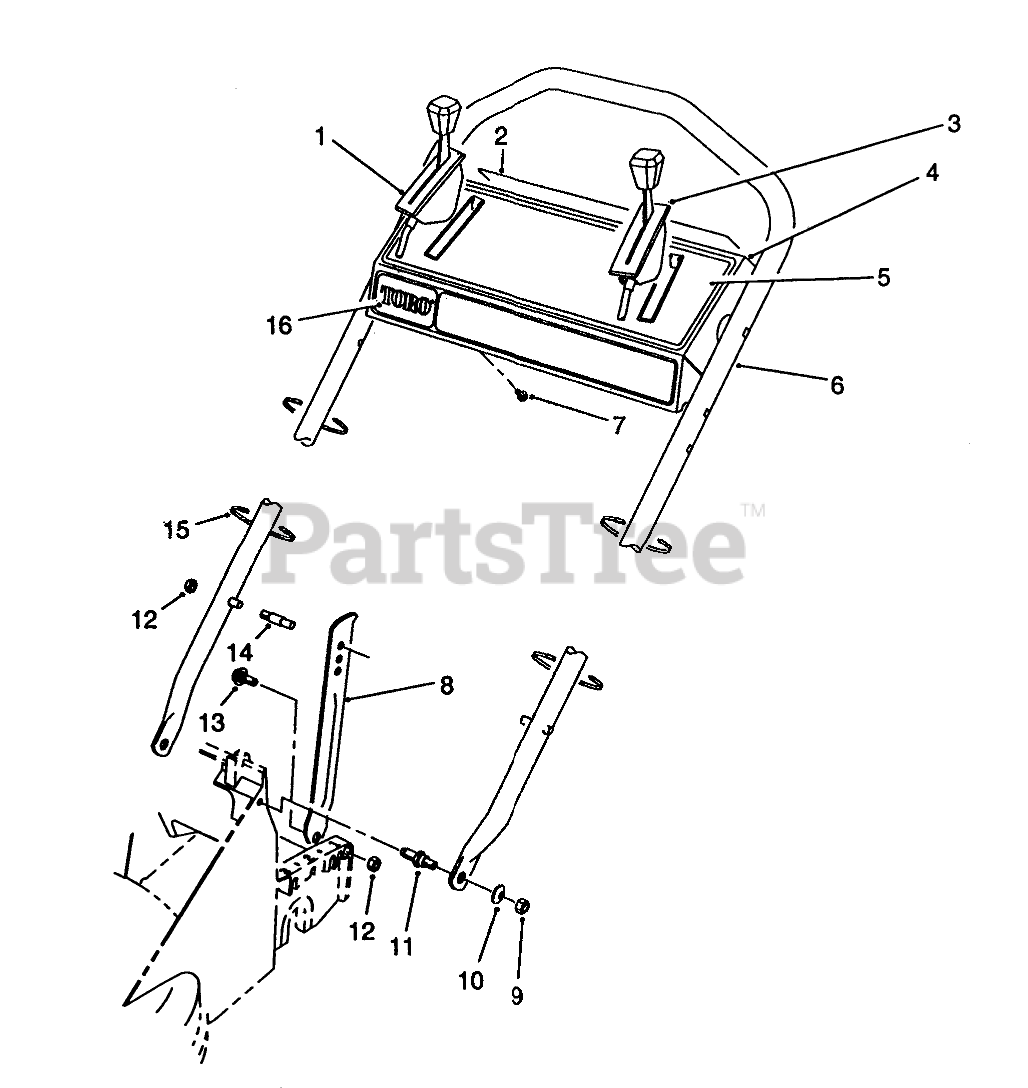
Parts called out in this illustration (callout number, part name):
1	GROUND SPEED CONTROL
2	DECAL-PANEL, DANGER
3	ControI-Throttle Bend Type #2 Sheath Lg. 44-3/4" Wire Lg. 2-1/2"
4	Control Panel Assembly (Incl. Ref. #2, 5 & 16)
5	DECAL - INSTRUCTION
6	HANDLE
7	SCREW-HWHTF
8	HANDLE LATCH
9	NUT-LOCK, NI
10	WASHER-PLAIN
11	SCREW - SHOULDER STUD
12	NUT-LOCK, NI
13	SCREW - SHOULDER
14	HANDLE PIN
15	TIE-CABLE
16	DECAL - TORO PANEL
